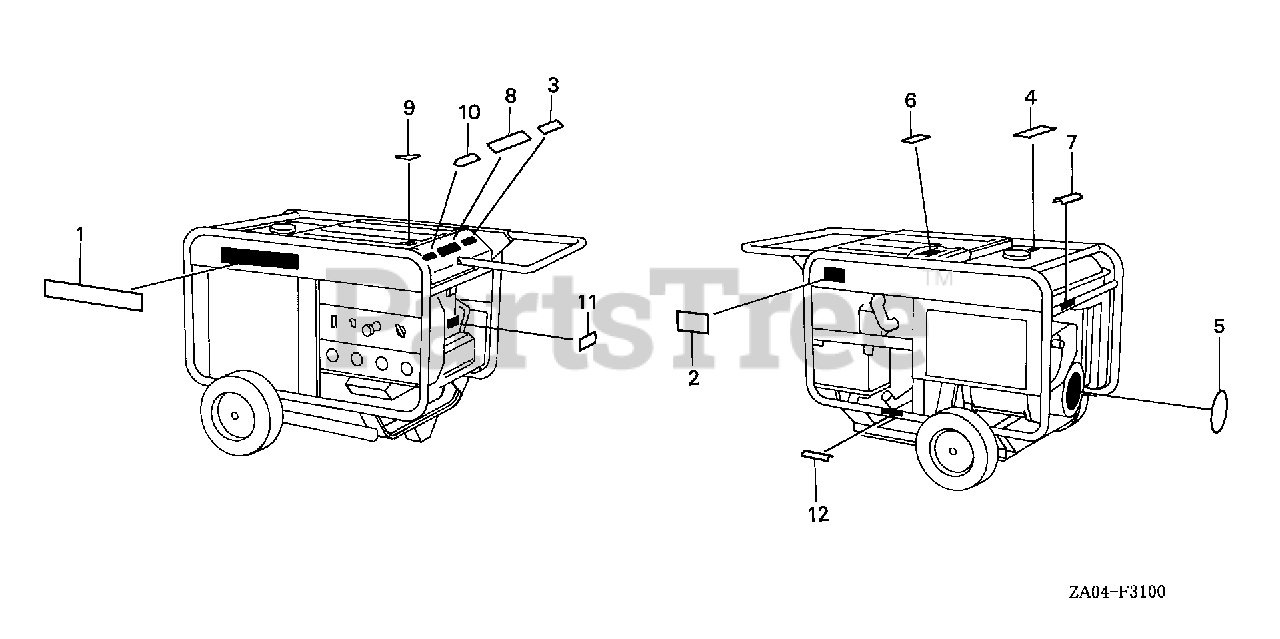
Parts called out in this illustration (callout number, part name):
1	EMBLEM (NOT AVAILABLE)
2	MARK, SPECIFICATION
4	MARK, CAUTION (ENGLISH/FRENCH/SPANISH)
5	LABEL, C.D.I. OIL ALERT
6	MARK, AIR CLEANER ARROW
7	MARK, EX. CAUTION (ENGLISH/FRENCH)
8	MARK, CAUTION
12	MARK, OIL CAUTION
